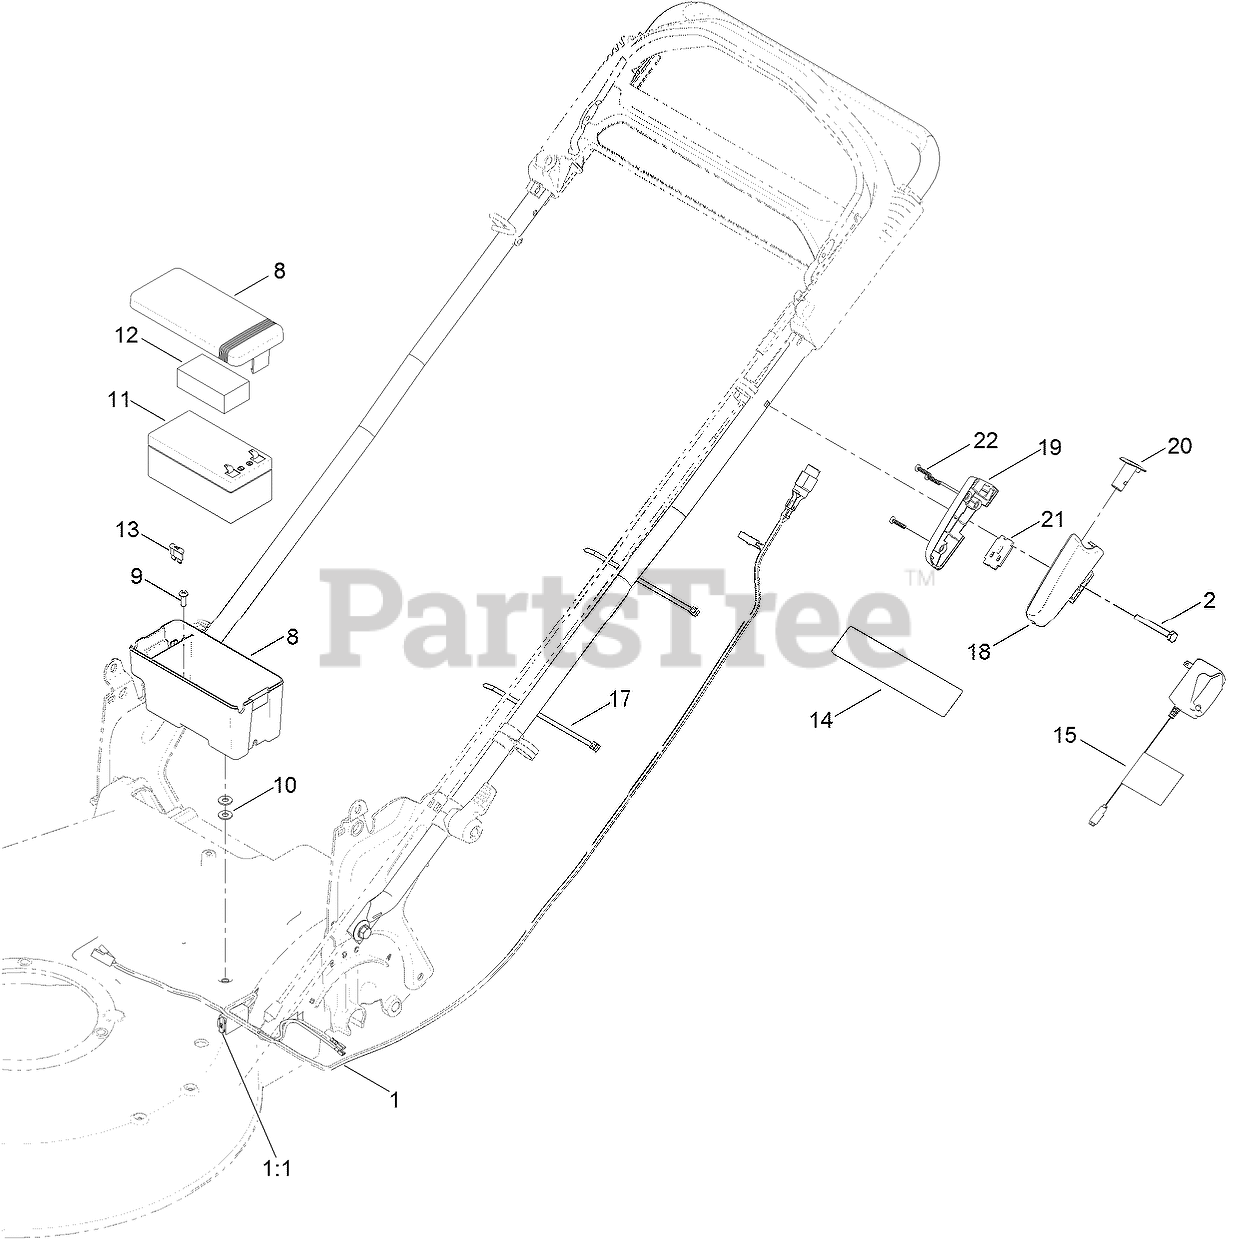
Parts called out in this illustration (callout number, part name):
1	HARNESS-WIRE
1:1	FUSE-40 AMP
2	SCREW-HH
8	BATTERY BOX ASM
10	WASHER-FLAT
11	BATTERY-WET
12	FOAM-BATTERY, TOP
13	FUSE-40 AMP
14	DECAL-WARNING
15	CHARGER-BATTERY
17	TIE-CABLE
18	HOUSING-SWITCH, LH
19	HOUSING-SWITCH, RH
20	BUTTON-SWITCH
21	SWITCH-PUSH BUTTON
22	SCREW-PPH
